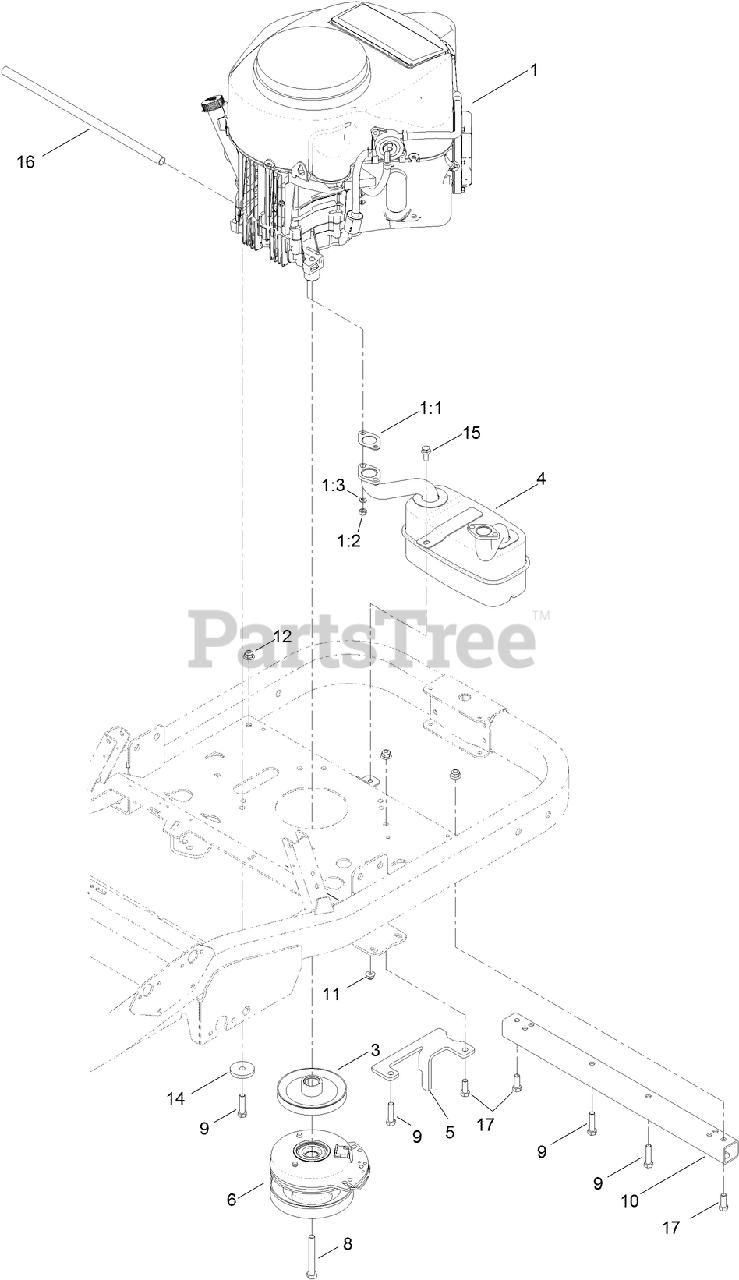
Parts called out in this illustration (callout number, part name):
1:1	GASKET-EXHAUST
1:3	WASHER-LOCK
3	PULLEY-ENGINE
4	MUFFLER
5	BRACKET-STOP, PTO
6	CLUTCH-PTO
8	SCREW-HH
9	BOLT-HH
10	TUBE-STIFFENER
11	NUT-HF, NI
12	NUT-HF, NI
14	WASHER-PLAIN
15	SCREW-HHF
16	TUBE-DRAIN, OIL
17	SCREW-HH
